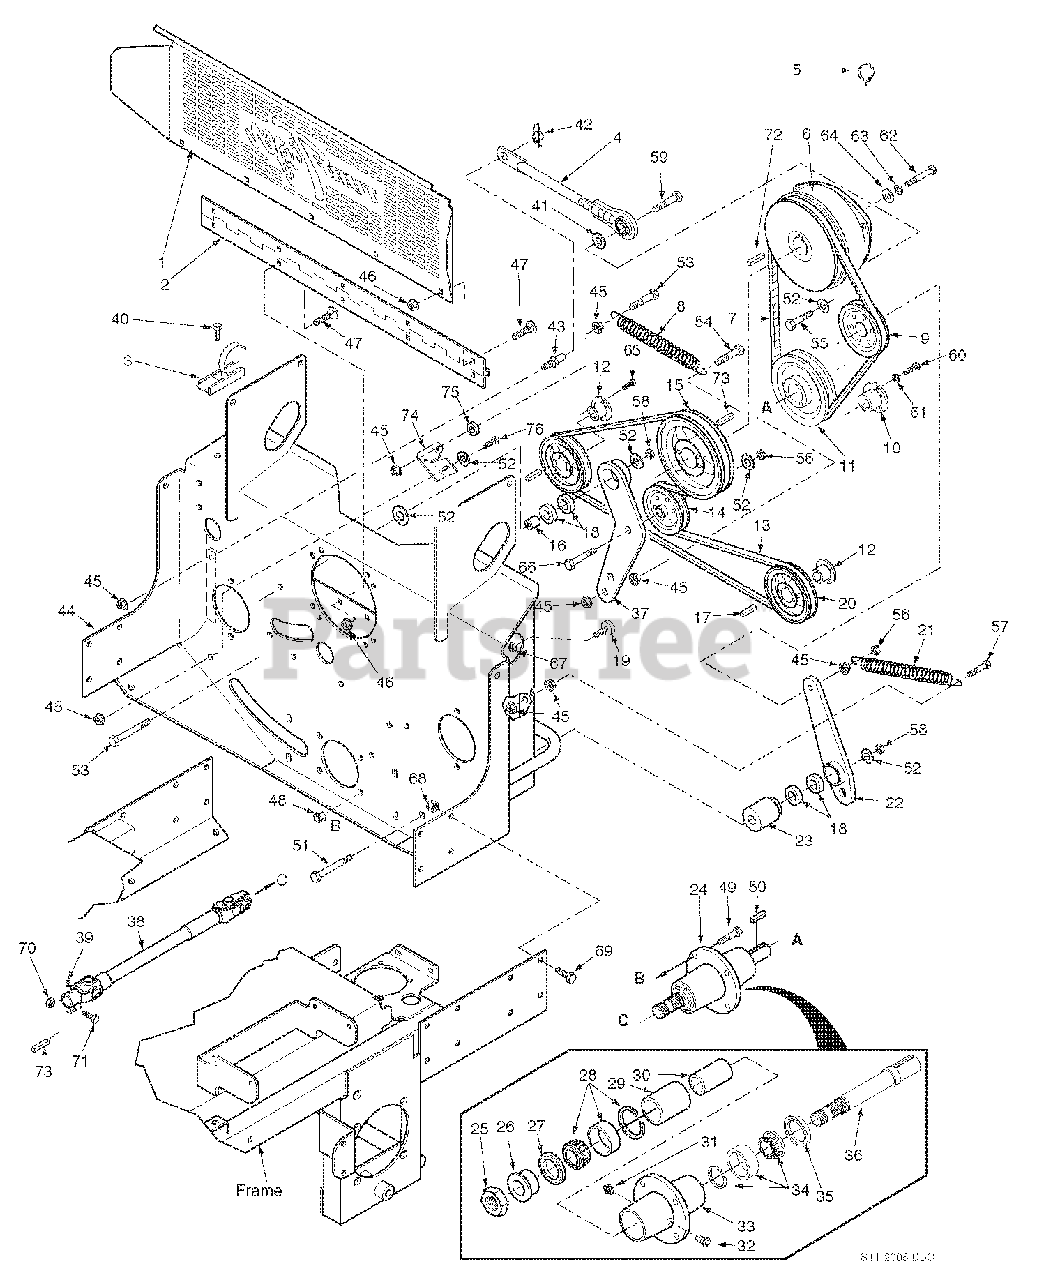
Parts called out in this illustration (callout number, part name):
1	Belt Guard, Rear
2	Hinge, Belt Guard
3	Latch, Hood
4	Rod Assembly, Clutch Anti-Rotation
5	Clamp, Cable
6	Clutch, Ogura GT-3.5
7	Belt, Deck Drive
8	Spring, Transmission Idler
9	Pulley, Idler 5" Dia.
10	Tapered Hub, 1" Bore
11	Pulley, 6.70" Tapered Bore
12	Tapered Hub, 17mm Bore
13	Belt, Pump Drive
14	Pulley, Idler 4" Dia.
15	Pulley, 5.367" Dia. - 1.125" Bore
16	Spacer, Idler Bearing
17	Key, 5.0 x 5.0 x 25mm
18	Ball Bearing
19	Bumper, Rubber
20	Pulley, 5.75" O.D.
21	Spring, PTO
22	Idler Arm Weldment, PTO Drive
23	Pivot, Idler PTO
24	Spindle Assembly, Deck Drive
25	Nut, 1.06-18 Thread
26	Spindle Bushing, Bottom
27	Seal, 2.0" O.D. x 1.625" Bore
28	Roller Bearing Tapered
29	Spacer, Outside
30	Spacer, Inside
31	Grease Fitting, 1/4-28
32	Relief Fitting
33	Spindle Housing
34	Roller Bearing Tapered
35	Seal, 2.0" O.D. x 1.5" Bore
36	Shaft, Deck Drive
37	Idler Arm Weldment, Pump Drive
38	Driveshaft
39	Set Screw, 3/8-16 x 3/4" Torx Socket
40	Screw, #10-32 x .56
41	Flatwasher, 3/8 (.391 x .938 x .105")
42	Pin, Rue Cotter 3/8" Dia.
43	Stud, Anti Rotation
44	Pump Mounting Plate Weld.
45	Nut, Serr. Flng. 3/8-16
46	Nut, Serr. Flng. 1/4-20
47	Bolt, Carriage 1/4-20 x 1/2"
48	Nut, Elastic Stop 5/16-18 Grd. 8
49	Bolt, Hex Hd. 5/16-18 x 1-3/4" Grd. 8
50	Key, 1/4 x 1/4 x 1-1/2"
51	Bolt, Hex Hd. 3/8-16 x 4-1/2" Grd. 8 Black
52	Washer, 3/8" Hardened
53	Bolt, Hex Hd. 3/8-16 x 1-3/4" Grd. 8 Black
54	Bolt, Hex Hd. 3/8-16 x 1-1/2" Grd. 8 Black
55	Bolt, Hex Hd. 3/8-16 x 2-1/2" Grd.8
56	Nut, Center Lock 3/8-16
57	Bolt, Hex Hd. 3/8-16 x 1-1/2" Grd. 8 Black
58	Nut, Elastic Stop 3/8-16
59	Bolt, Hex Hd. 3/8-16 x 2"
60	Bolt, Hex Hd. 1/4-20 x 1-3/8"
61	Lockwasher, 1/4" Spring
62	Bolt, Hex Hd. 7/16-20 x 2-1/2" UNF
63	Lockwasher, 7/16" Spring
64	Flatwasher, 7/16 (.469 x 1.75 x .25")
65	Bolt, Hex Hd. 1/4-20 x 1" Grd. 8
66	Bolt, Hex Hd. 3/8-16 x 1-3/4"
67	Nut, Serr. Flng. 5/16-18
68	Nut, Elastic Stop 3/8-16
69	Bolt, Hex Hd. 3/8-16 x 1"
70	Nut, Center Lock 3/8-16
71	Bolt, Hex Hd. 3/8-16 x 1-3/4"
72	Key, 1/4 x 1/4 x 2-1/4"
73	Key, 1/4 x 1/4 x 1"
74	Bracket
75	Spacer
76	Bolt, Hex Hd. 3/8-16 x 1"
